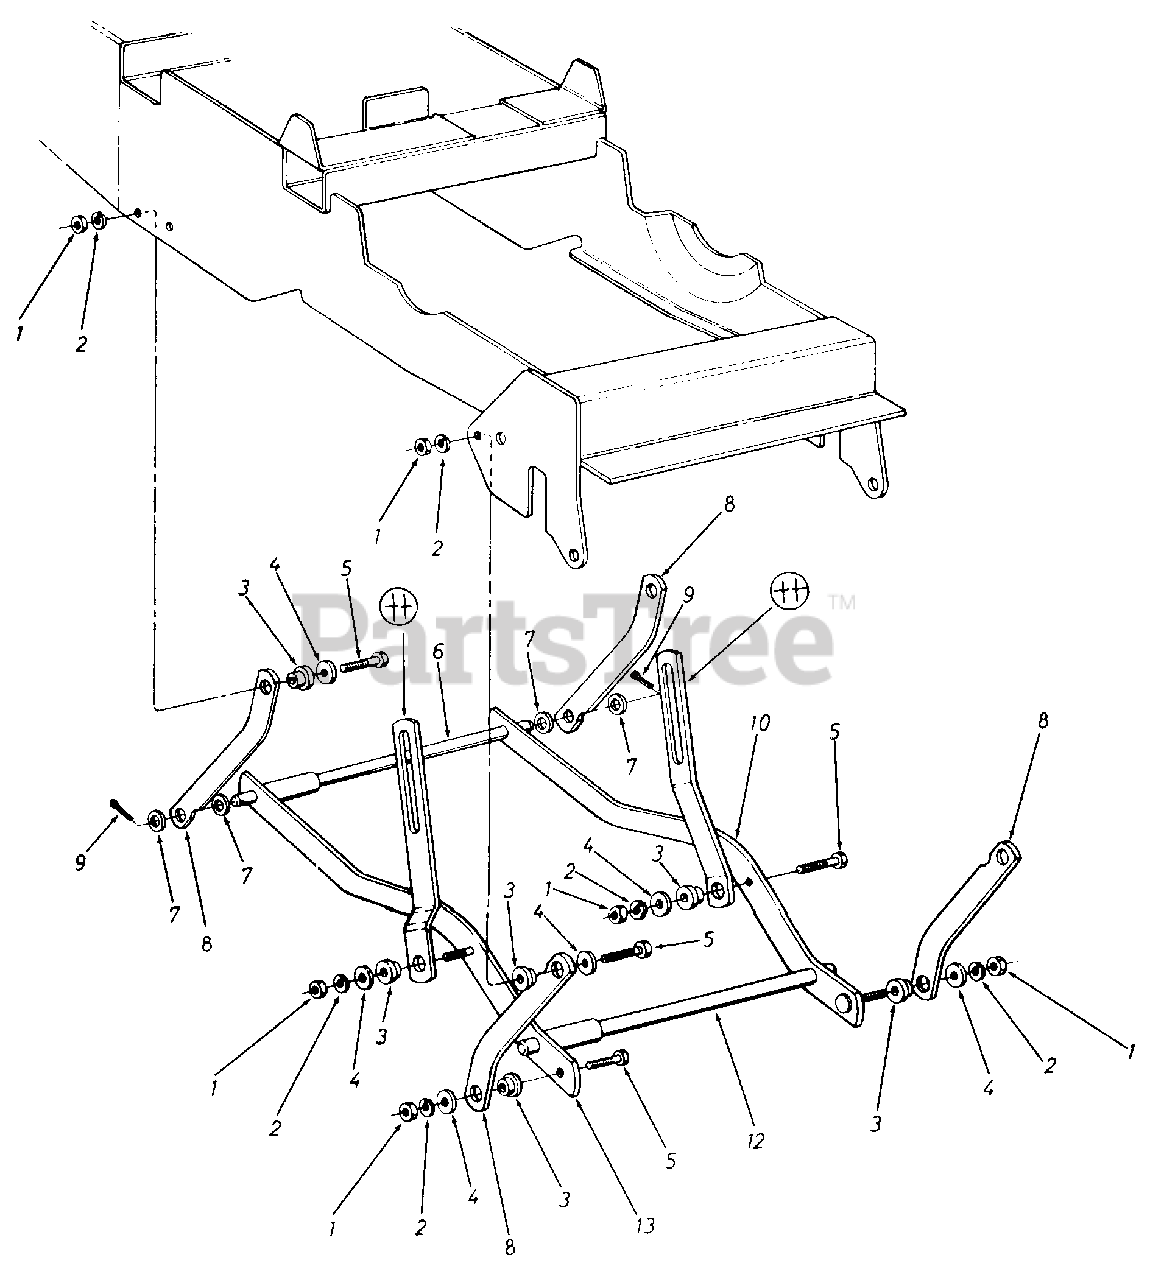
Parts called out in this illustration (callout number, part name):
1	Hex Nut 3/8-24 Thd.*
2	L.-Wash. 3/8" Scr. Heavy Duty
3	Shoulder Spacer
4	Fl.-Wash. 3/8" I.D. x 1.0" O.D.
5	Hex Scr. 3/8-24 x 1.50" Lg. Grade 5
6	Cross Shaft Ass'y.-Rear
7	Fl.-Wash. 5/8" I.D. x 1-1/8" O.D.
8	Lift Arm
9	Cotter Pin 5/32" Dia. x 1.25" Lg.
10	Lift Arm Link Ass'y.-L.H.
11	Hair Pin Cotter
12	Cross Shaft Ass'y.-Front
13	Lift Arm Link Ass'y.-R.H.
